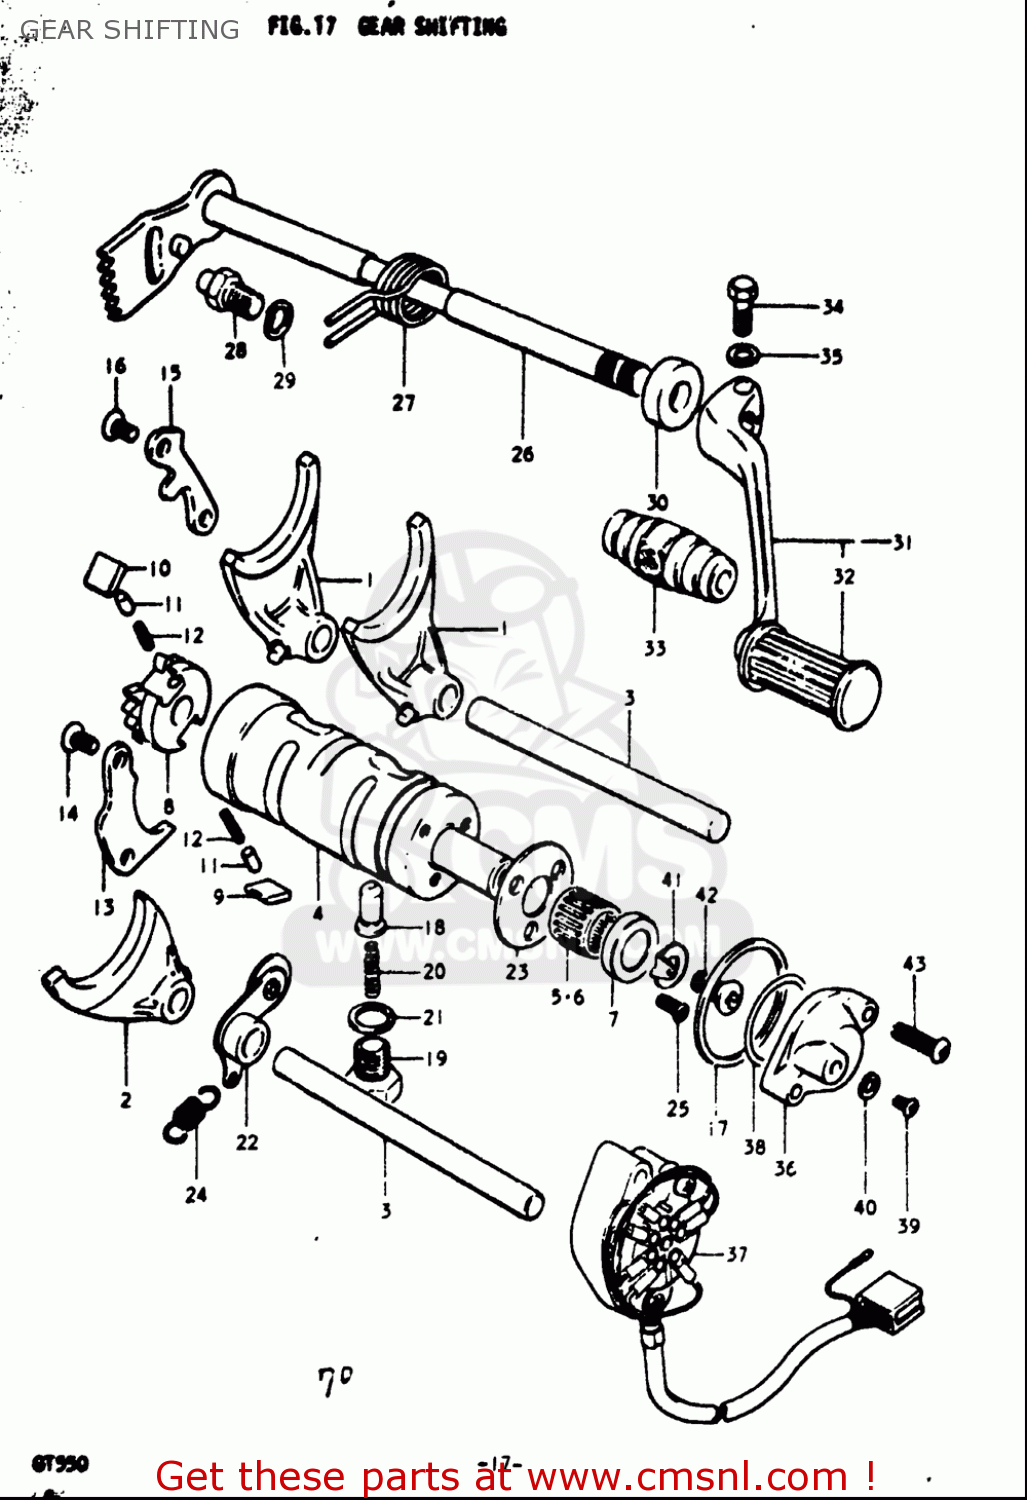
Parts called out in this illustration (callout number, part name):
1	FORK,GEAR SHIFT NO.1
2	FORK,GEAR SHIFT NO.3
3	SHAFT,GEAR SHIFT FORK
5	ROLLER BEARING (16X22X1
6	BEARING(16X22X12)
7	SEAL,OIL(16X24X7)
8	GEAR,GEAR SHIFT CAM DRIVEN
9	PAWL,GEAR SHIFT NO.1
10	PAWL,GEAR SHIFT NO.2
11	PIN(5X8)
12	SPRING
13	LIFTER,GEAR SHIFT PAWL
14	SCREW
15	GUIDE,GEAR SHIFT
16	SCREW
17	WASHER(40X45X1)
18	STOPPER,GEAR SHIFT CAM NO.2
19	HOLDER,GEAR SHIFT CAM STOP SPR
20	SPRING
21	GASKET(14X19.2X2) (NAS)
22	STOPPER,GEAR SHIFT CAM
24	SPRING
25	SCREW
27	SPRING
28	STOPPER,GEAR SHIFT ARM
29	WASHER,LOCK
30	SEAL,OIL (12X22X9)
31	LEVER ASSY,GEAR SHIFT
32	RUBBER,GEAR SHIFT PEDAL
33	RUBBER,GEAR SHIFT PEDAL
34	BOLT
35	WASHER,LOCK
36	BODY,GEAR SHIFT SWITCH
38	O RING(D:1.9,ID:27.7)
39	SCREW
40	WASHER
41	CONTACT,GEAR SHIFT SWITCH
42	SCREW
43	SCREW
